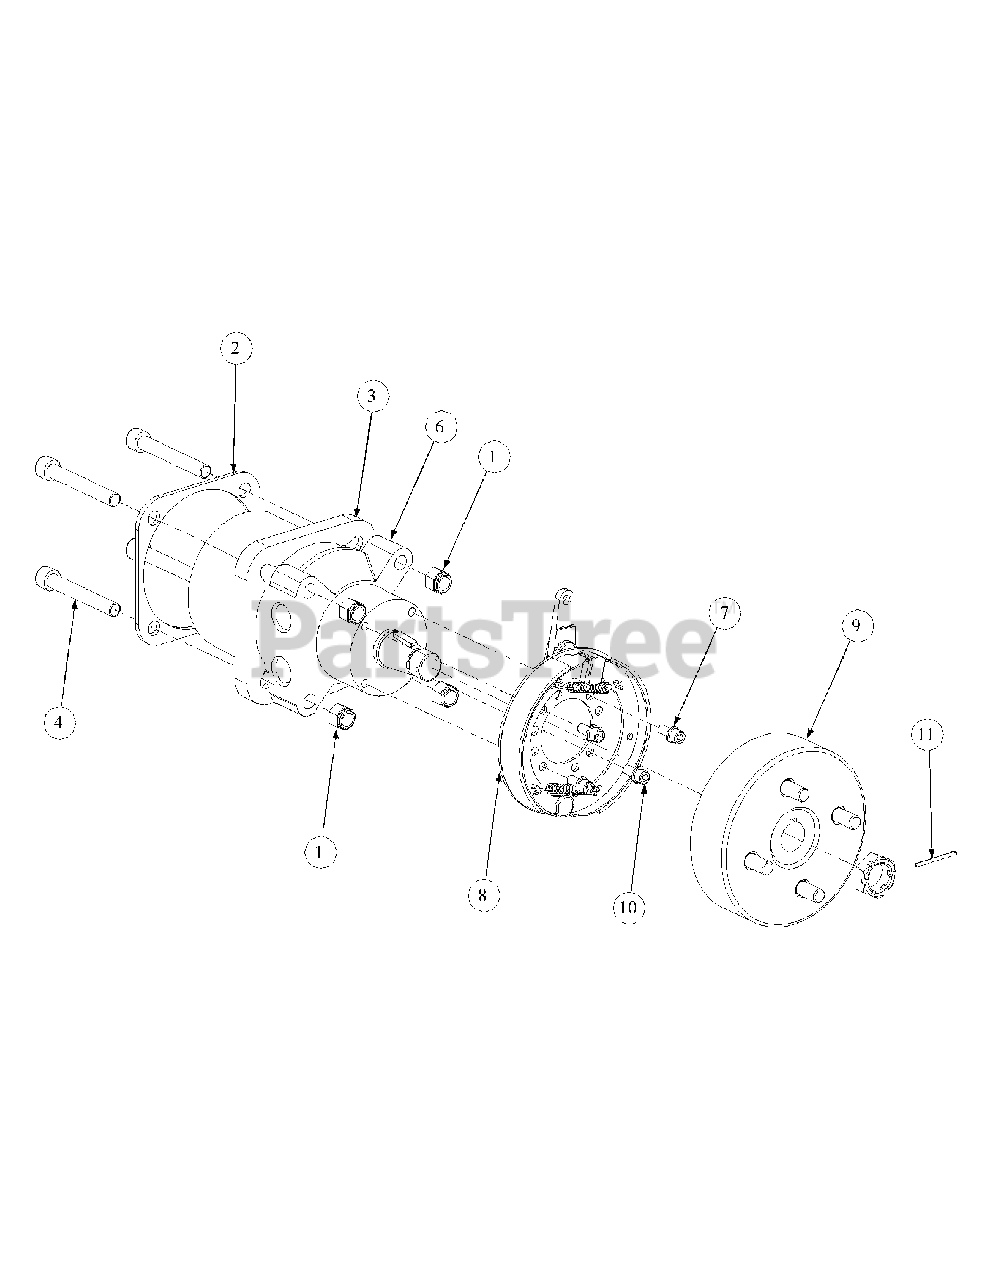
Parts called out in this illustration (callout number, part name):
1	Lock Nut, Nylon Insert, 1/2-13
2	Motor Plate
3	Motor Spacer
4	Socket Head Capscrew, 1/2-13; 3-1/2
4	Capscrew, 1/2-13 x 3.5
5	Hyd. Motor, Parker Left Hand
6	Hydro Motor, Parker Right Hand
7	Lock Washer, 5/16
8	Brake Assembly w/Line
9	Hub and Drum Assembly w/Studs
10	Capscrew w/Socket, 5/16-18 x 3/4
11	Cotter Pin 1/8 x 1-1/2
